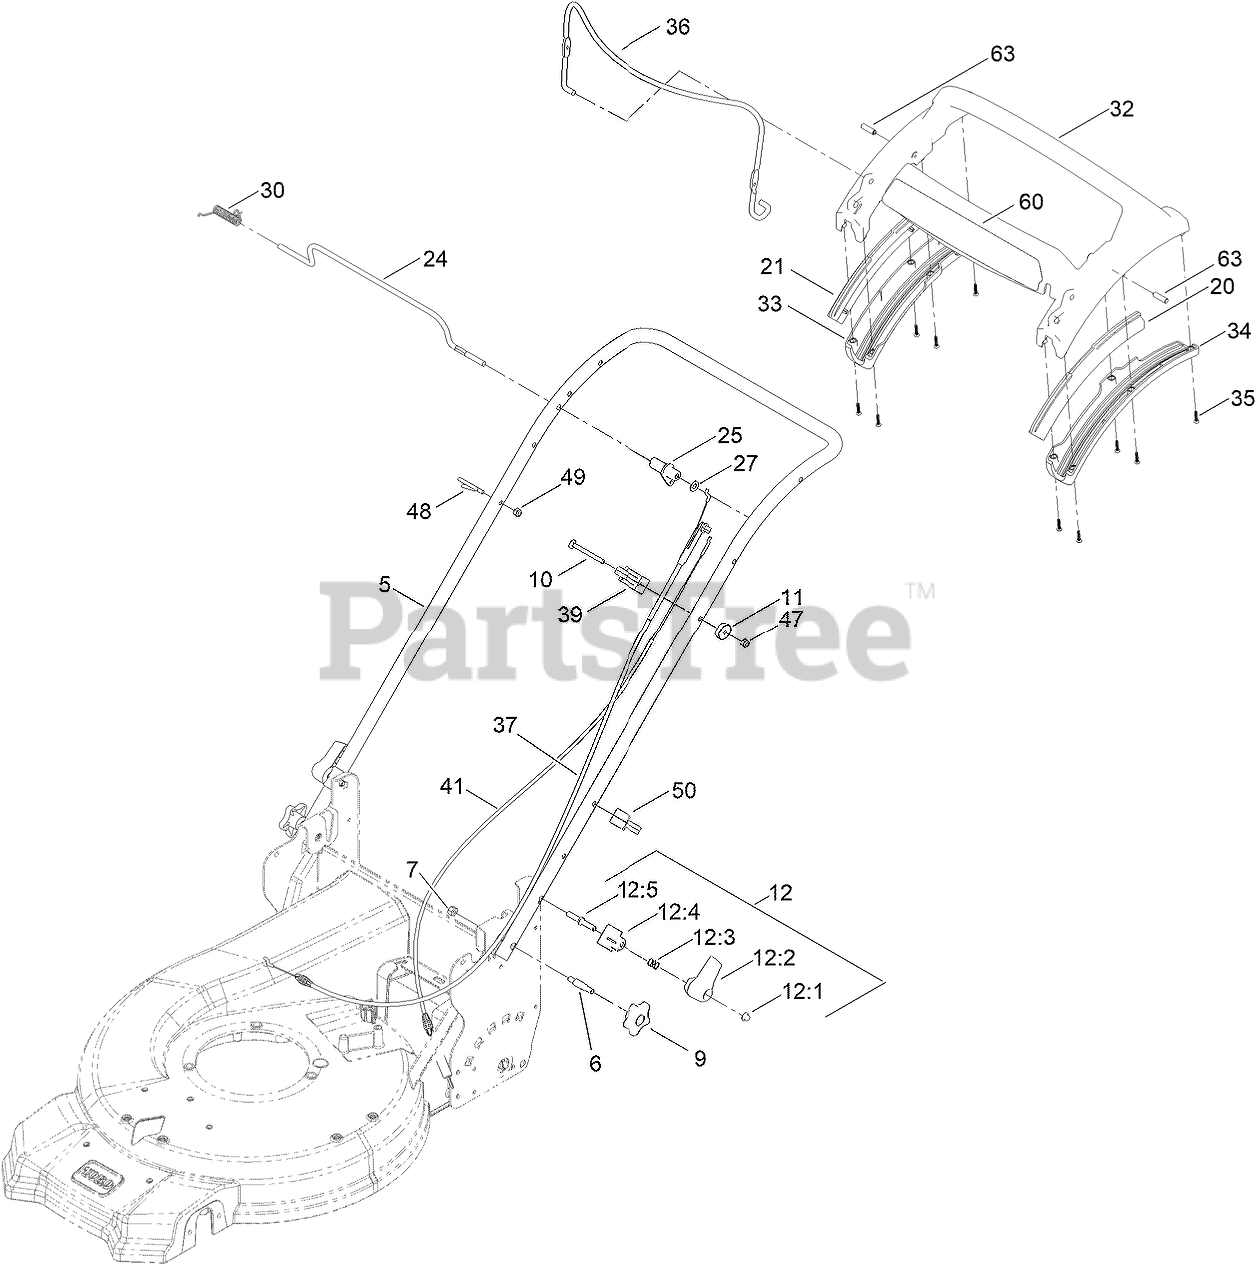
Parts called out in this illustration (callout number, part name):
5	HANDLE-CURVED
6	BOLT-SHOULDER, HANDLE
7	NUT-LOCK, NI
9	KNOB-HANDLE
10	SCREW-CARR
11	WASHER-CURVED
12	QUICK RELEASE ASM
12:1	NUT-PUSH
12:2	LEVER-RELEASE
12:3	ANCHOR-SPRING
12:4	SPRING-COMPRESSION
12:5	ROD-RELEASE
20	GUIDE-CURVED, LH (RWD)
21	GUIDE-CURVED, RH (RWD)
24	ROD-CONTROL, TRACTION
25	LEVER-TRACTION, RWD
27	WASHER-PLAIN
30	SPRING-TORSION
32	HANDLE-PERSONAL PACE, CURVED
33	BOTTOM-HANDLE, RH
34	BOTTOM-HANDLE, LH
35	SCREW-PPH
36	BAIL-BRAKE
37	CABLE-BRAKE, PP BS
39	ANCHOR-CABLE, RWD
41	CABLE-TRACTION, RWD (PP)
47	NUT-LOCK, NI
48	GUIDE-ROPE
49	NUT-HEX
50	GUIDE-CABLE
60	DECAL-HANDLE, PP
63	PIN-HANDLE, PP
